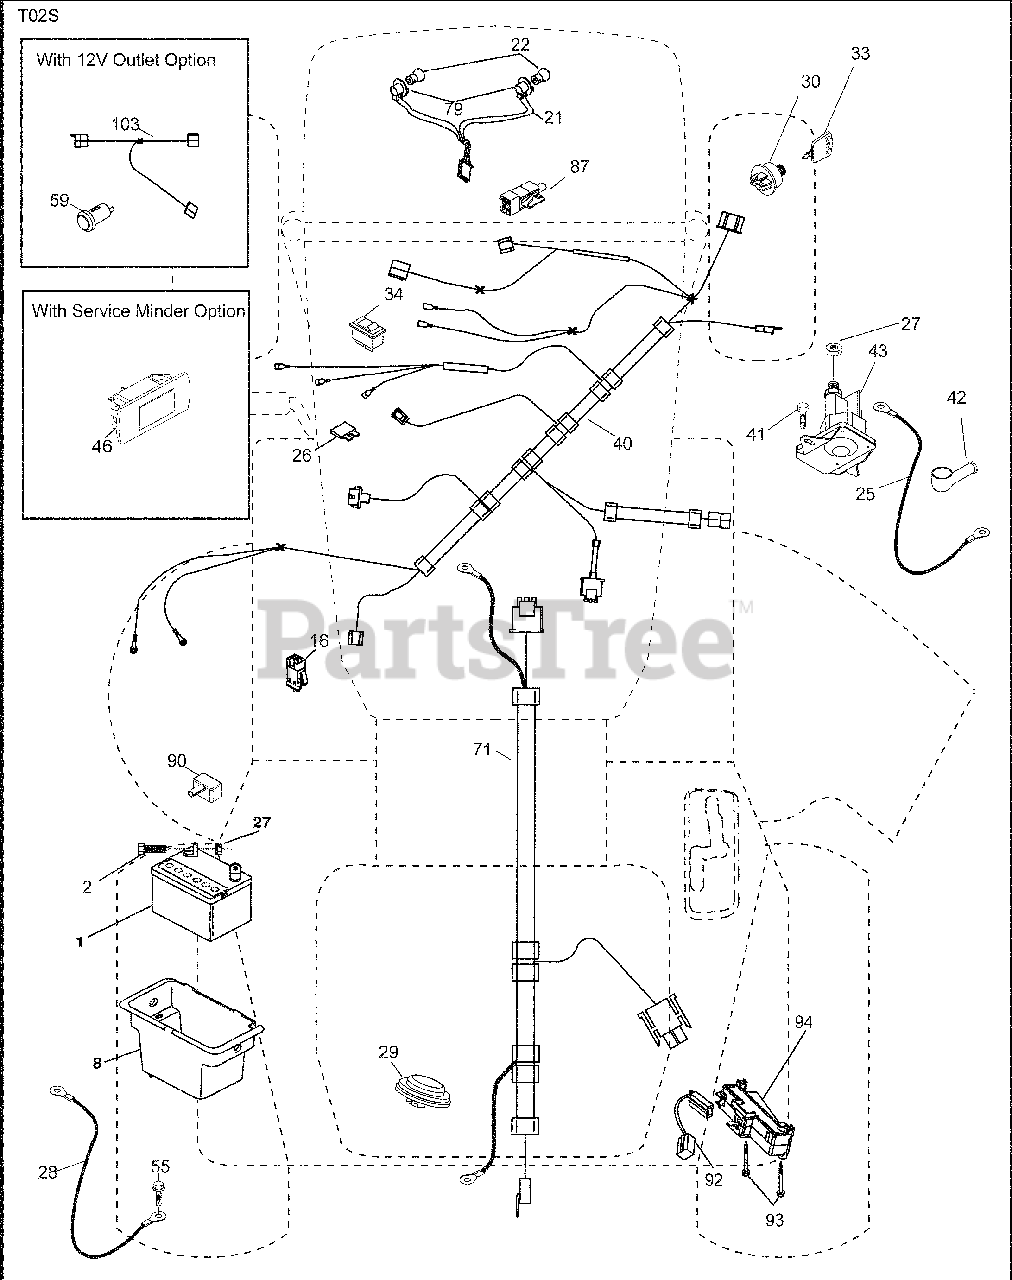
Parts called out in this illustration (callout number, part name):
1	Battery
2	Bolt Hex Head 1/4-20 x 3/4
8	Box Battery
16	Switch Interlock Push-In
21	Harness Socket Light w/4152J
22	Bulb Light
25	Cable Starter
27	Nut Keps Hex 1/4-20 unc
28	Cable, Ground
29	Switch, Seat
30	Switch, Ign
34	Switch Light/Reset
40	Harness Ign. Dash
41	Screw Thd Cut 1/4-20 x 1/2
42	Cover, Terminal
43	Solenoid
55	Screw Thdrol 5/16-18 x 3/4
71	Harness Chassis
79	Socket Asm Bulb Twistlock
87	Switch Interlock Clutch Cable
90	Cover, Terminal Battery
92	Harness Pigtail Reverse Switch
93	Screw Plastite 10-14 x 2.0
94	Module Reverse ROS
